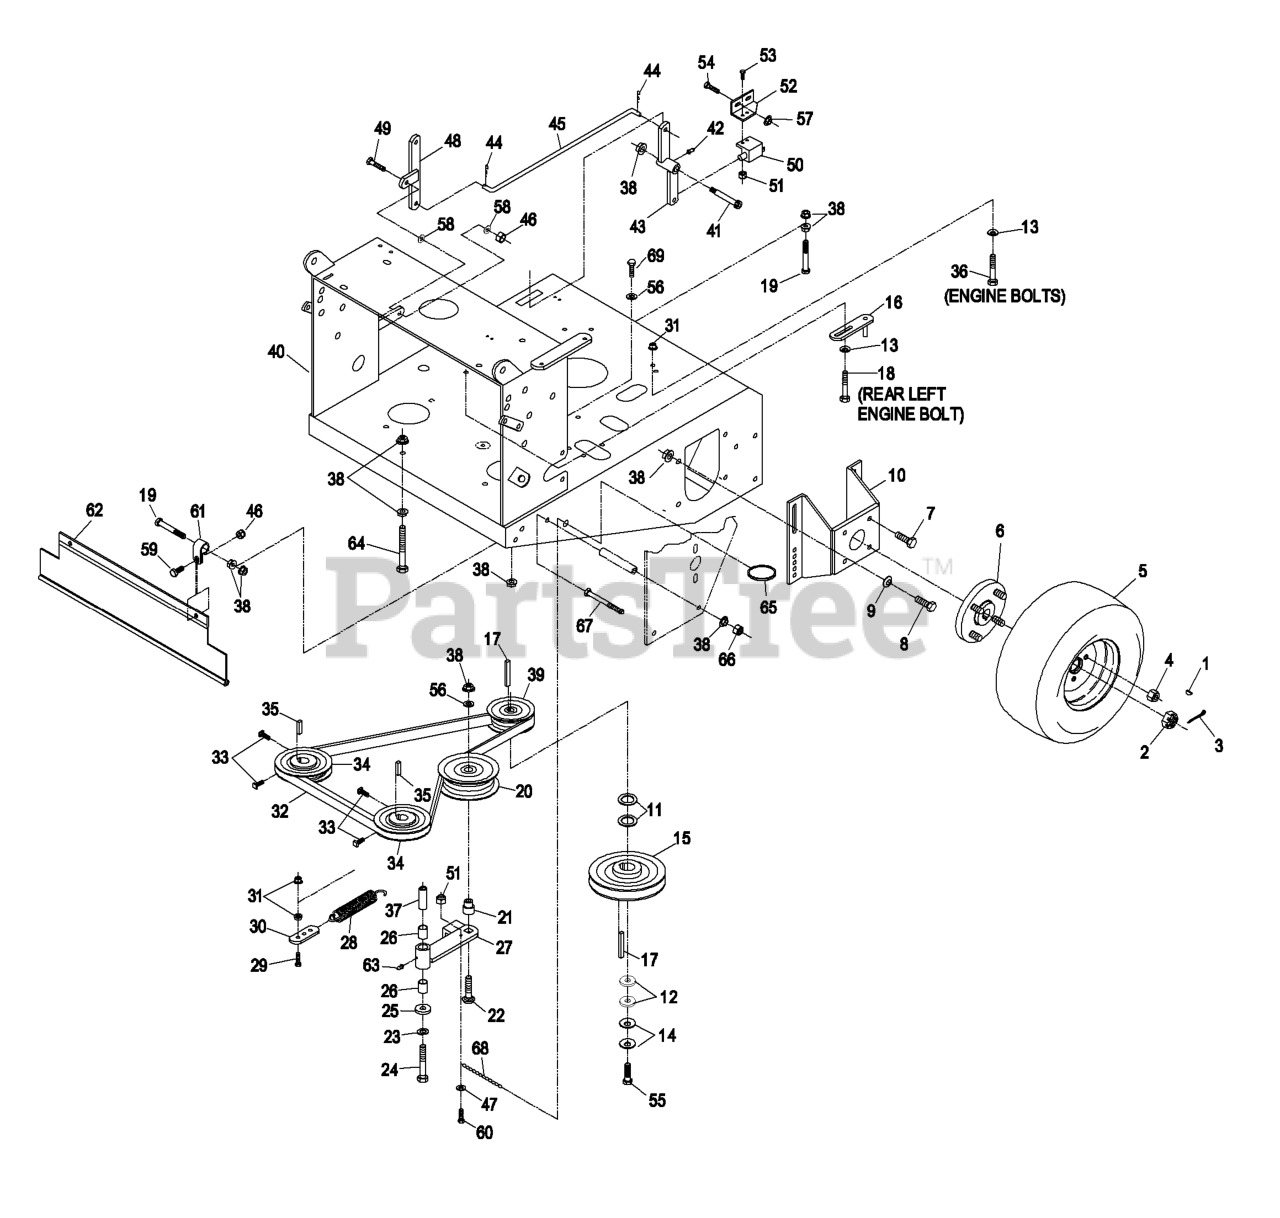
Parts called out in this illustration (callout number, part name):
1	KEY-WOODRUFF
3	PIN-COTTER
4	NUT-LUG
5	WHEEL AND TIRE ASM
7	SCREW-HHF
8	SCREW-HH
9	WASHER-BELLEVILLE
10	MOUNT-MOTOR
11	WASHER-SPACER
13	WASHER-SPRING
14	WASHER-SPRING
16	GUIDE-BELT
18	SCREW-HH
19	SCREW-HH
21	BUSHING-IDLER
22	SCREW-CARR
23	WASHER-LOCK
24	BOLT-CARR
26	SLEEVE-BEARING
27	IDLER ARM ASM
28	SPRING-EXTENSION
29	SCREW-HH
30	ANCHOR-SPRING
33	SCREW-SET
34	SHEAVE ASM
36	SCREW-HH
37	BUSHING
38	NUT-HHF, WHIZ
39	PULLEY
42	FITTING-GREASE, 90 DEG
43	BELLCRANK ASM
44	PIN-COTTER
45	LINKAGE-ENGAGE, BLADE
46	NUT-LOCK, NI
47	WASHER-FLAT
49	SCREW-HH
50	SWITCH-OPEN, NORMALLY
51	NUT-LOCK, NI
52	BRACKET-SWITCH, BLADE
53	SCREW-PPH
54	SCREW-HH
55	SCREW-HH
56	WASHER-FLAT
58	WASHER-PLAIN
59	SCREW-HH
60	SCREW-HSH
61	CLIP-LOOM
62	SHIELD-DRAG
63	FITTING-GREASE
64	SCREW-HH
65	RING-SPLIT
66	NUT-LOCK, NI
67	SCREW-HH
68	CHAIN-LINK, TWIST
69	SCREW-HH
